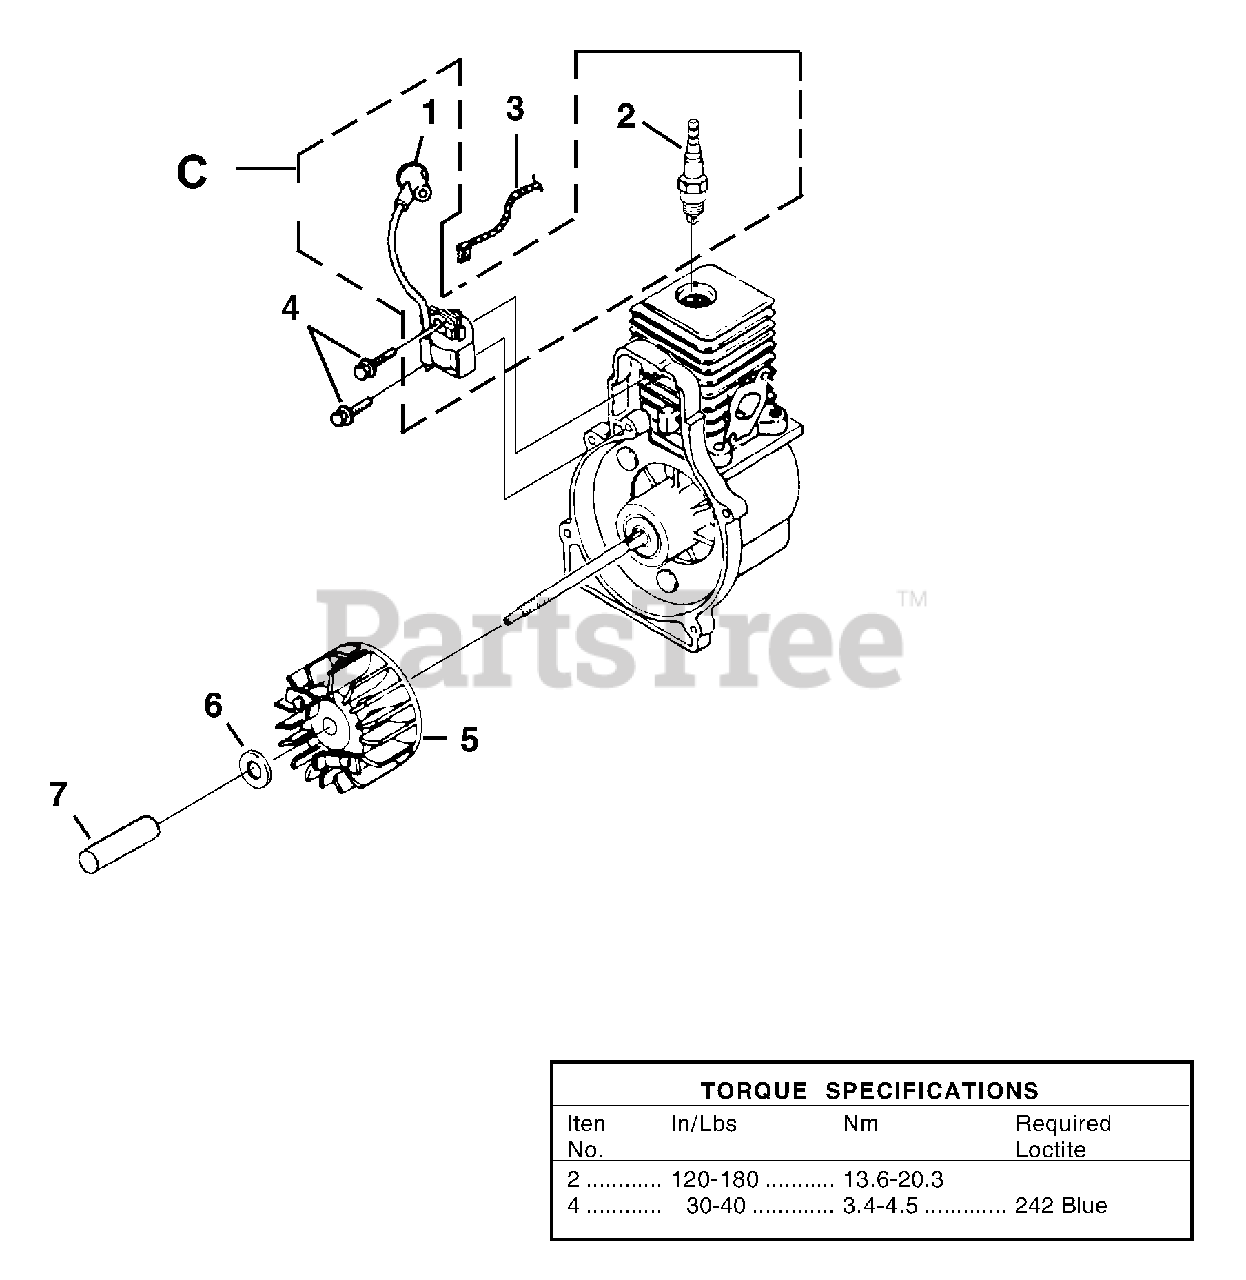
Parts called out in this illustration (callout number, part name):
1	TERMINAL-Hi-Tension
2	SPARK PLUG (RDJ-7Y)
3	CABLE-Throttle w/Ignition Leads
4	SCREW-Thread Form. (8-32 x 1")
5	ROTOR & STARTER PAWLS
6	WASHER-Flat
7	SPACER-Fan
C	IGNITION KIT w/ Module
